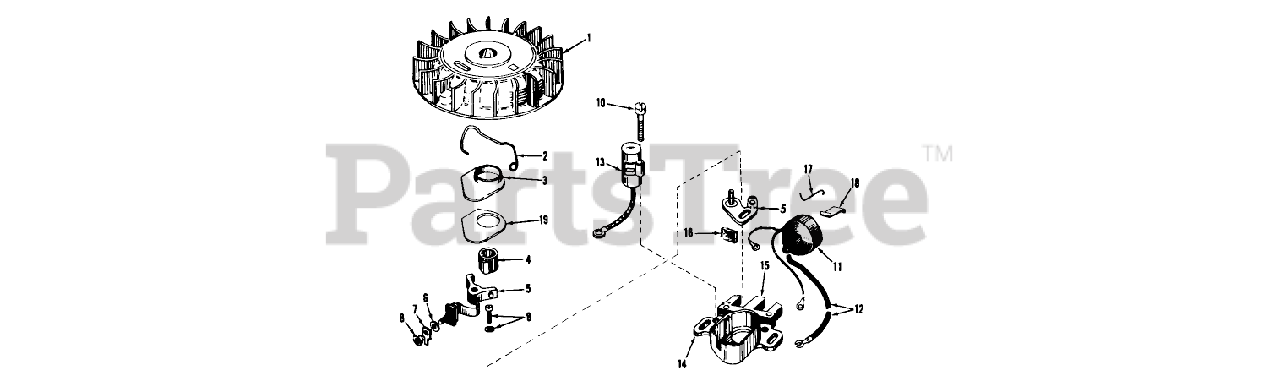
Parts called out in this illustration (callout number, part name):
1	Flywheel
2	Spring Breaker Box
3	Cover, Dust
4	Cam-Breaker
5	Breaker Assy.
6	Washer
7	Terminal
8	DECAL
9	Breaker Screw
10	Condenser Screw
11	Coil Assy., (Inc. Ref. Nos. 12, 13 18)
12	Wire, Lead
13	Condenser
14	Core Plate
15	Stator Assy., (Incl. Nos. 2, 3, 5 thru 14 16 thru 19)
16	Felt,Cam Wiper
17	Clip, Coil
18	Spring Coil Wedge
19	Gasket Dust
